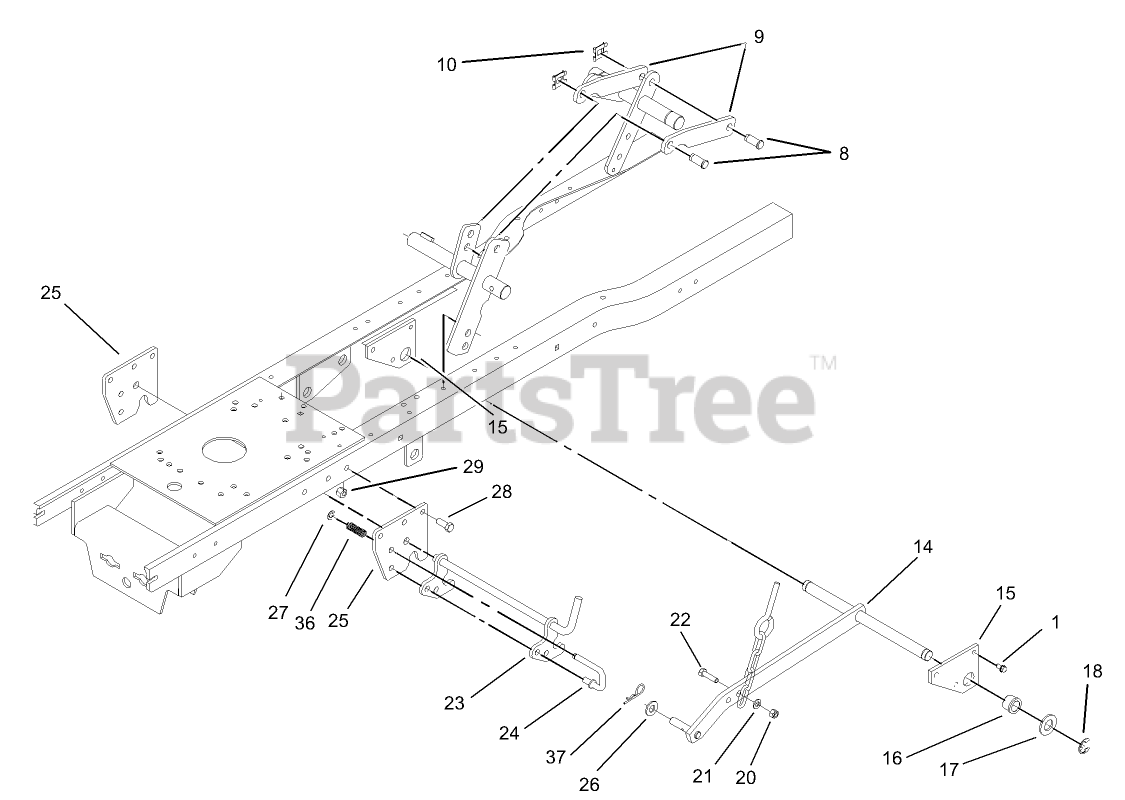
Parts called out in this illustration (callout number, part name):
1	SCREW-HWHTF
8	PIN-CLEVIS
9	STRAP-LINK, LIFT
10	CLIP-PIN
14	LIFT BAR ASM
15	PLATE-LIFT, REAR
16	BUSHING-FLANGE
17	WASHER-FLAT
18	E-RING
20	NUT-LOCK, NI
21	WASHER-PLAIN
22	SCREW-HH
23	MIDHITCH LATCH ASM
24	ROD-CATCH, MIDHITCH
25	PLATE-HITCH
26	WASHER-FLAT
27	RING-RETAINING
28	SCREW-HH
29	NUT-LOCK, NI
36	SPRING
37	PIN-HAIR
